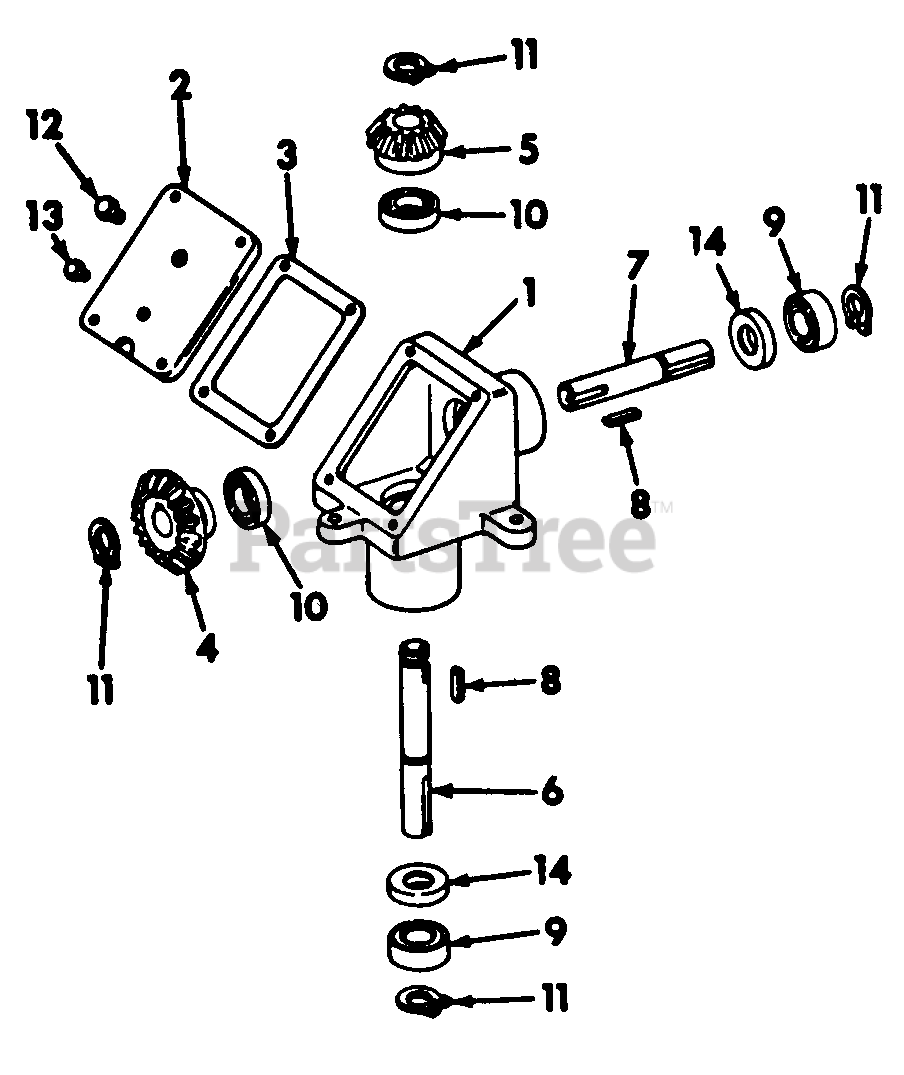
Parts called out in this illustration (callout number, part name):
2	Cover, Gear Box
3	Gasket, Gear Box Cover
4	Gear, Bevel - 30 Tooth
5	Gear, Bevel - 20 Tooth
6	Shaft, Input
7	Shaft, Output
8	Key, 3/16 X 11/16 Sq Parallel
9	Bearing, Ball
10	Bearing, Ball
11	Ring, Retaining
12	Plug, Automotive 1/8 Npt Sq-Hd
13	Plug, Automotive 1/4 Npt Sq-Hd
